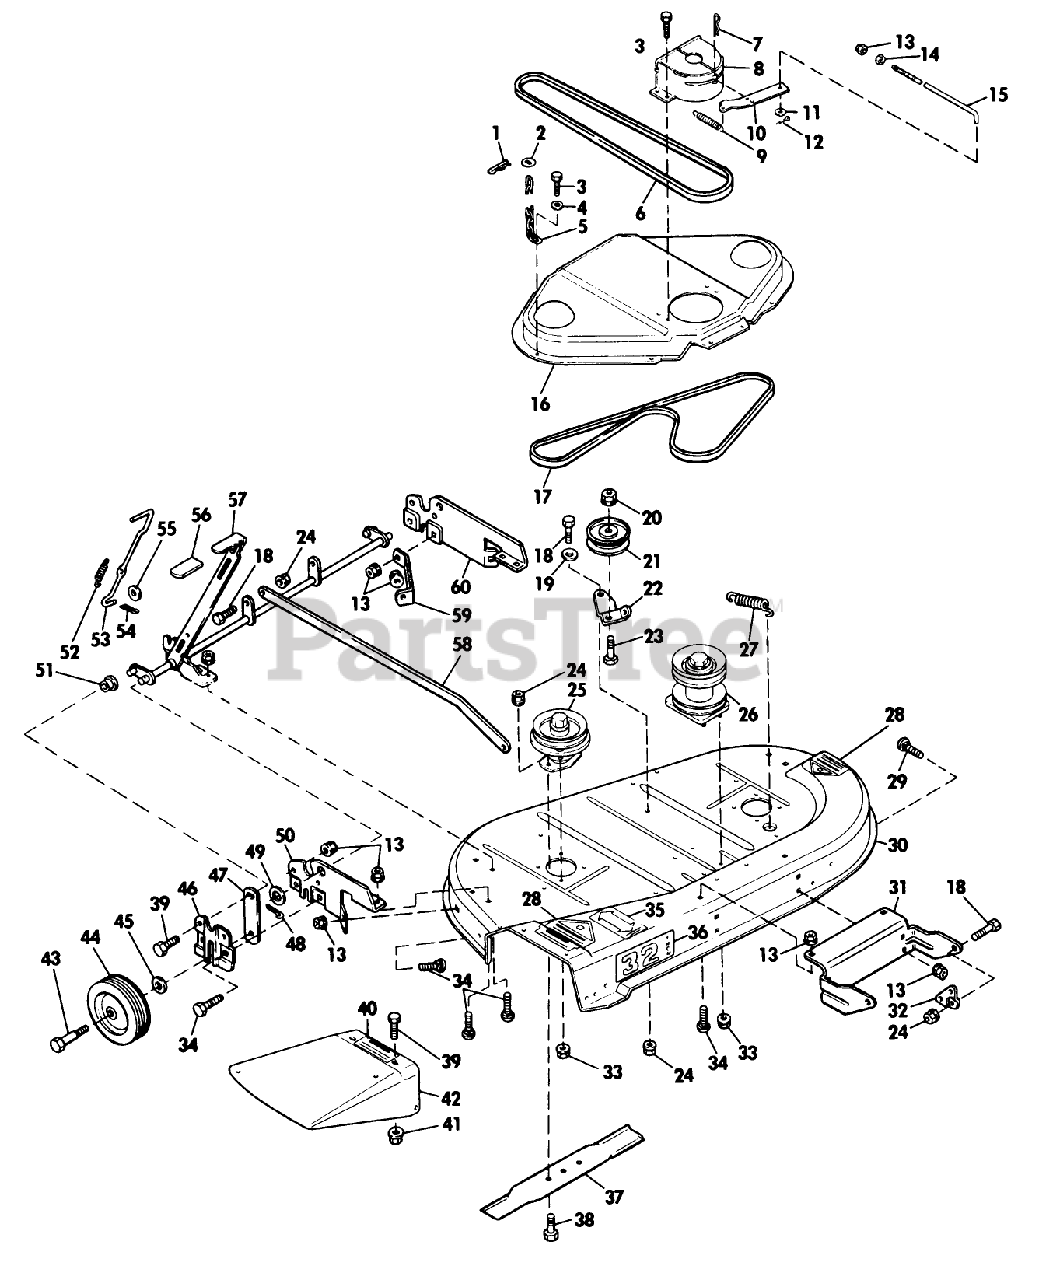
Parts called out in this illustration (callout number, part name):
1	Clip-Hairpin
2	Washer
3	Screw-Belt Cover
4	WASHER
5	Chain
6	V-Belt
7	Clip-Hairpin-Blade Brake Lever
8	Guard Belt
9	Spring-Brake-Blade
10	Lever-Brake Blade
13	NUT
14	Nut-Jam-Blade Brake Rod
15	Rod-Brake Blade
16	Cover-Blade Housing
17	V-Belt-Blade Drive
18	Screw
21	Pulley-Idler
22	Lever-Idler
23	Screw-Idler Pulley
24	Nut
25	Spindle Assembly
26	Spindle Assembly
27	Spring-Idler
28	Decal-Caution Pan
29	Bolt
30	Housing-Blade
31	Bracket-Blade Housing
32	Pivot-Blade Housing
33	Locknut-Large Flange
34	Bolt
35	Decal-Blade Positions
36	Decal-32 Inch
37	Blade
38	Screw
40	Decal-Caution
41	STOP NUT
42	Deflector
43	Screw
44	Wheel Tire Assembly
46	Retainer-Height Adj. Slide
47	Slide-Height Adjuster
48	Cotter Pin
49	Washer-Height Adjuster
50	Bracket-Wheel Mounting R.H.
51	Bushing-Height Adjuster
52	Spring-Latch
53	Latch-Slide
54	Pin
55	WASHER
56	Grip-Handle
57	Shaft Assembly Height Adjustment
58	Bar-Parallel
59	Brace-Wheel Mounting L.H.
60	Bracket-Wheel Mounting L.H.
